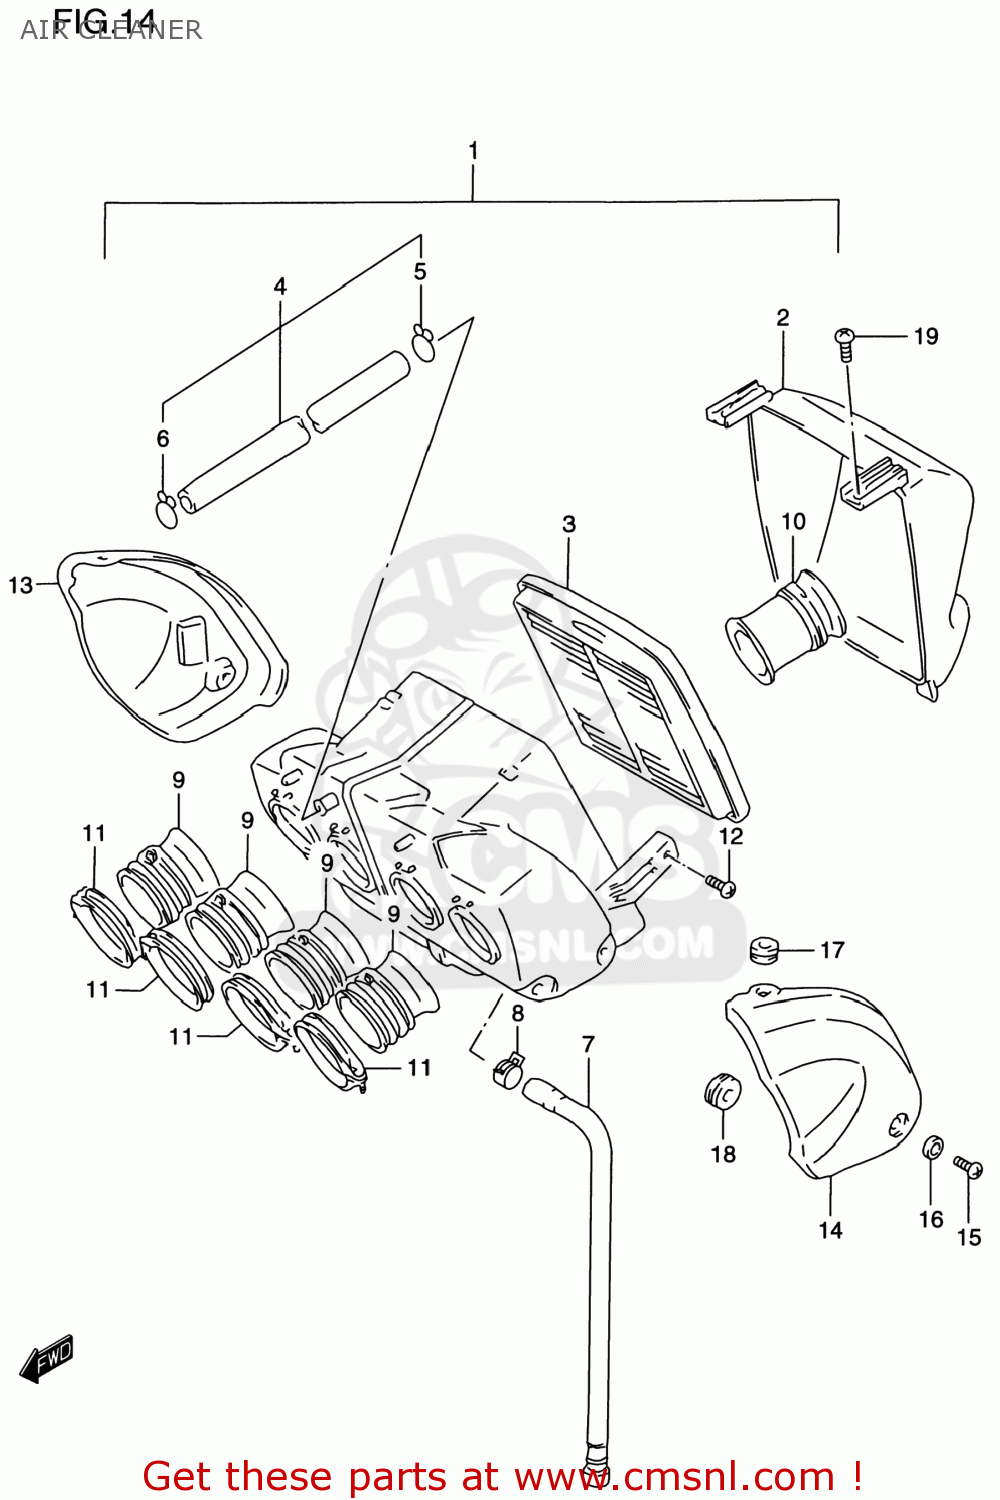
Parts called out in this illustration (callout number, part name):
1	CLEANER ASSY,AIR
2	CAP,AIR CLEANER
3	FILTER,AIR
4	TUBE,BREATHER
5	CLIP
6	CLIP
7	TUBE,DRAIN
8	CLIP
9	TUBE,OUTLET
10	TUBE,INLET
11	CLAMP
12	SCREW
13	COVER COMP,AIR CLEANER,RIGHT
14	COVER COMP,AIR CLEANER,LEFT
15	SCREW(5X14)
16	WASHER
17	CUSHION
18	CUSHION
19	SCREW 6X12
